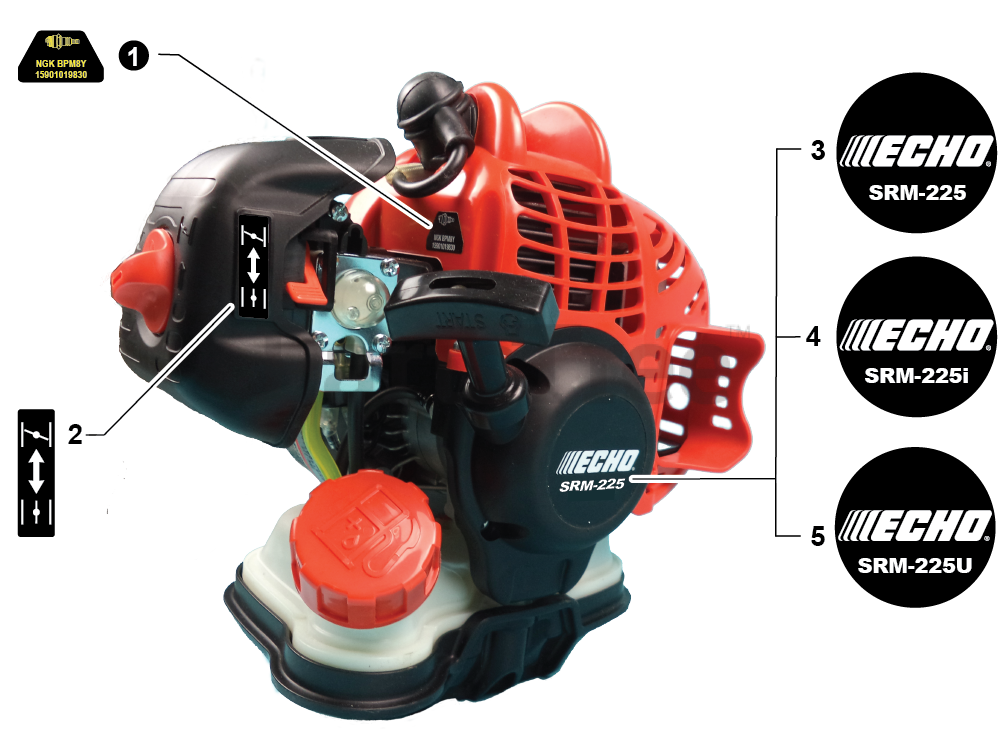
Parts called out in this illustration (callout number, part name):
1	LABEL - SPARK PLUG - BPM8Y
2	LABEL - CHOKE
3	LABEL - STARTER - SRM-225
4	LABEL - STARTER - SRM-225I
5	LABEL - STARTER - SRM-225U
